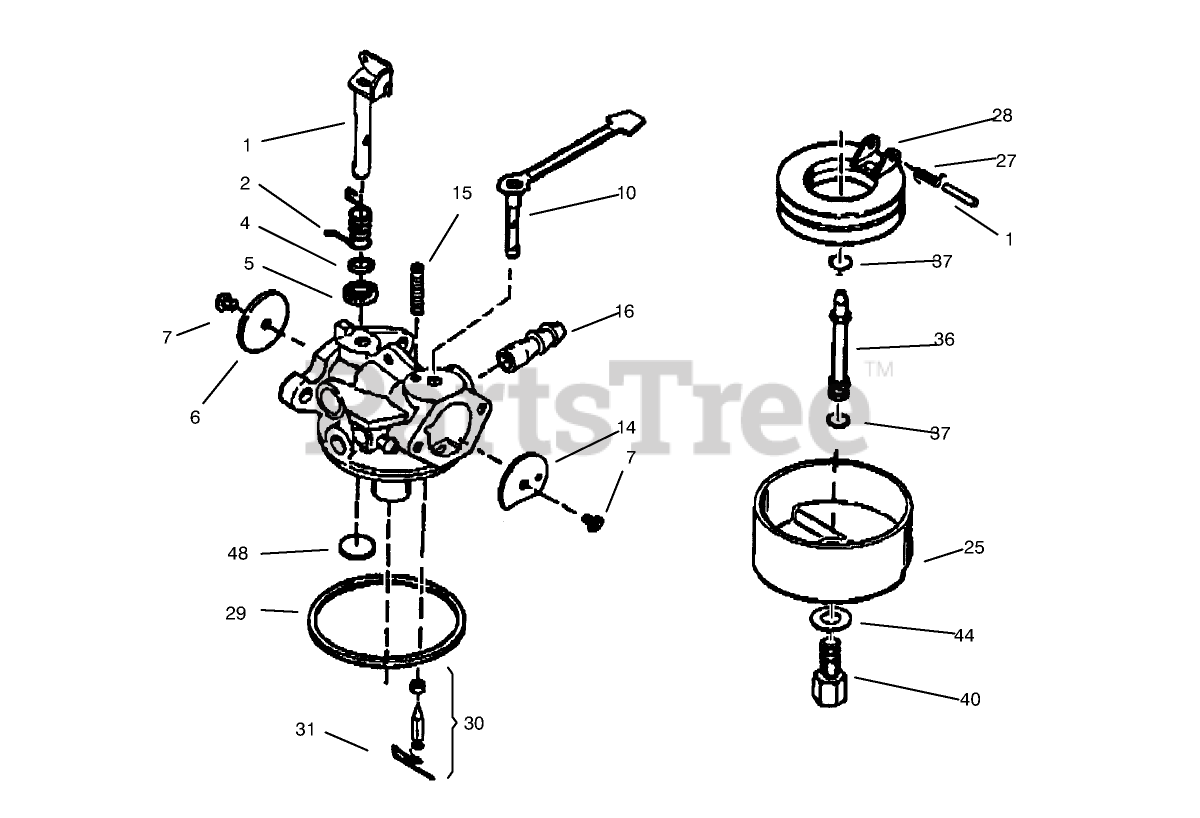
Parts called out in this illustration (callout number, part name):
1	Throttle Shaft and Lever ASM
2	Spring-Trottle, Return
4	Washer-Seal, Dust
5	Seal-Dust
6	Shutter-Throttle
7	Screw-Shutter
10	Choke Shaft and Lever ASM
14	Shutter-choke
15	Spring-Positioning, Choke
16	Fitting-Fuel
25	Bowl Float
26	Spring-Float, Dampening
27	Shaft-Float
28	Float
29	O Ring-Bowl, Float
30	Inlet Needle, Seat Clip Assy. (Incl. No. 13)
31	Clip-Spring
36	Tube-Nozzle, Main
37	O-Ring
40	Nut-Bowl, High Speed
44	Washer-Bowl Nut
48	Plug-Welch, Atmospheric Vent
